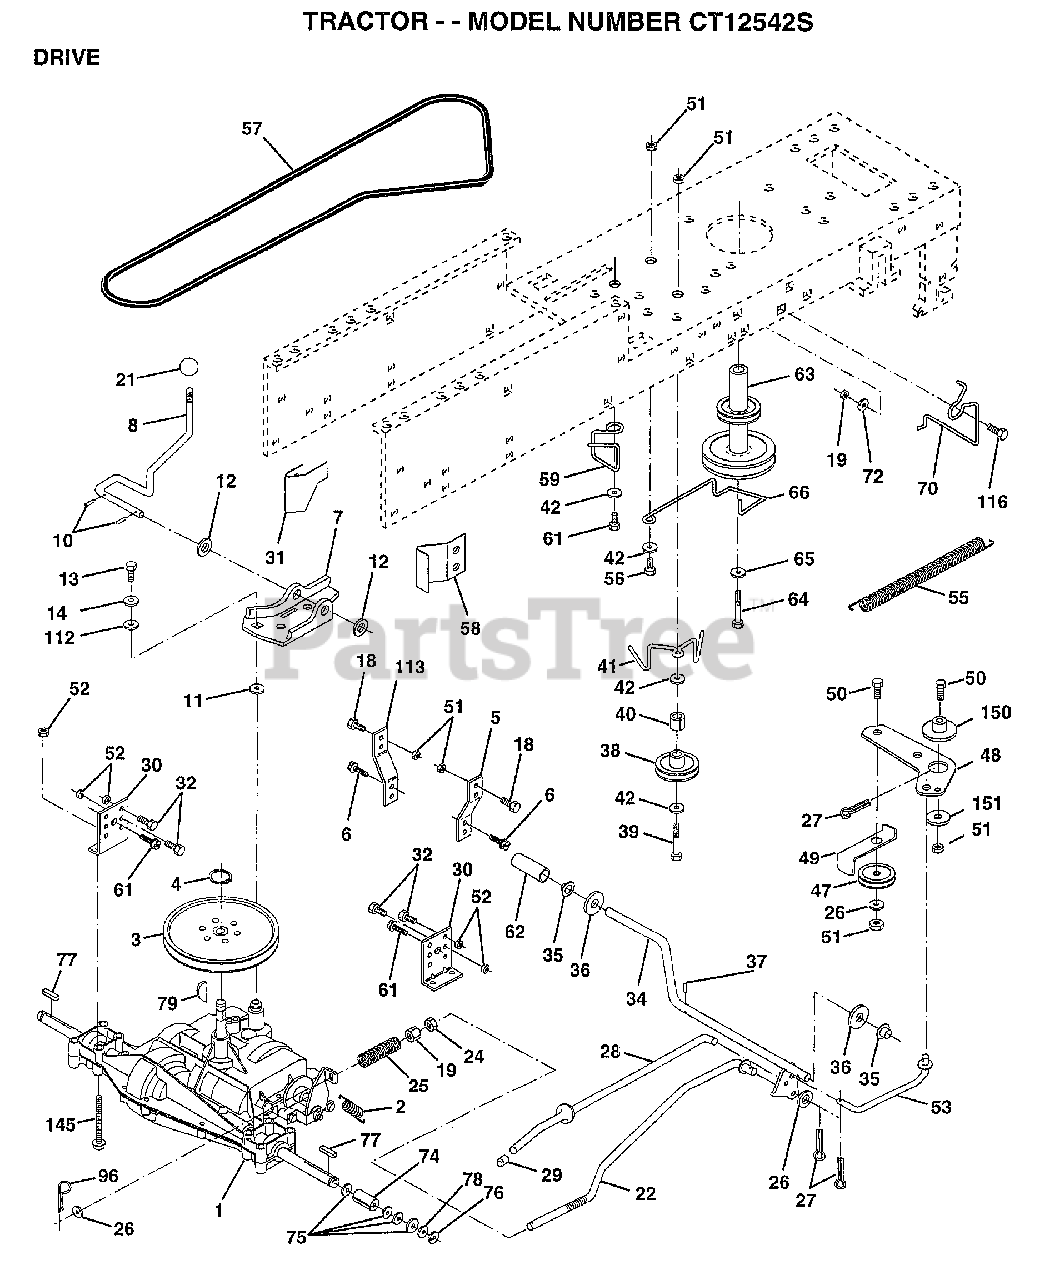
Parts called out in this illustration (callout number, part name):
2	SPRING.BRAKE.RETU
3	PULLEY TRANS
5	STRAP TORQUE
6	SCREW
7	BRKT.SADDLE.SHIFT
8	SHIFT ROD
10	PIN COTTER 1/8
11	WASH-SHFT PLT LT
12	WASHER
13	BOLT.1/4-28.W/PAT
14	LOCKWASHER
18	BOLT
19	NUT
21	KNOB T (1/2-HOLE)
22	BRAKE ROD
24	NUT
25	SPRING ROD LT
26	WASHER
27	COTTER PIN
28	ROD.BRAKE.PARK.LT
29	PLUNGER CAP T
30	TRANSAXLE MTG BKT
31	"KEEPER,BELT LH T"
32	BOLT
34	SHAFT ASM-PEDAL F
35	NYLON BEARING
36	WASHER LT
38	FLAT IDLER PULLEY
39	BOLT
40	SPACER T
41	"KEEPER,BELT.IDLER FLAT"
42	WASHER
48	BELLCRANK.CLUTCH
49	RETAIN BELT
53	"LINK, CLUTCH T"
55	"SPRING, RETURN LT"
58	"KEEPER,BELT RH T"
59	KEEPER BELT CNTSP
61	SCREW
62	PEDAL COVER T
63	PULLEY.ENGINE
64	BOLT
65	LOCKWASHER
66	KEEPER-BELT
70	KEEPER BELT ENG
72	WASHER
74	SPACER AXLE
75	WASHER
76	E-RING LT
77	SQUARE KEY
78	WASHER
96	RETAINER M
112	WASHER LT
113	"STRAP,TORQUE"
116	BOLT RDHD 3/8-16
145	BOLT.HEX.FLGHD
150	BUSHING.BELLCRANK.GRD.DR
151	WASHER
